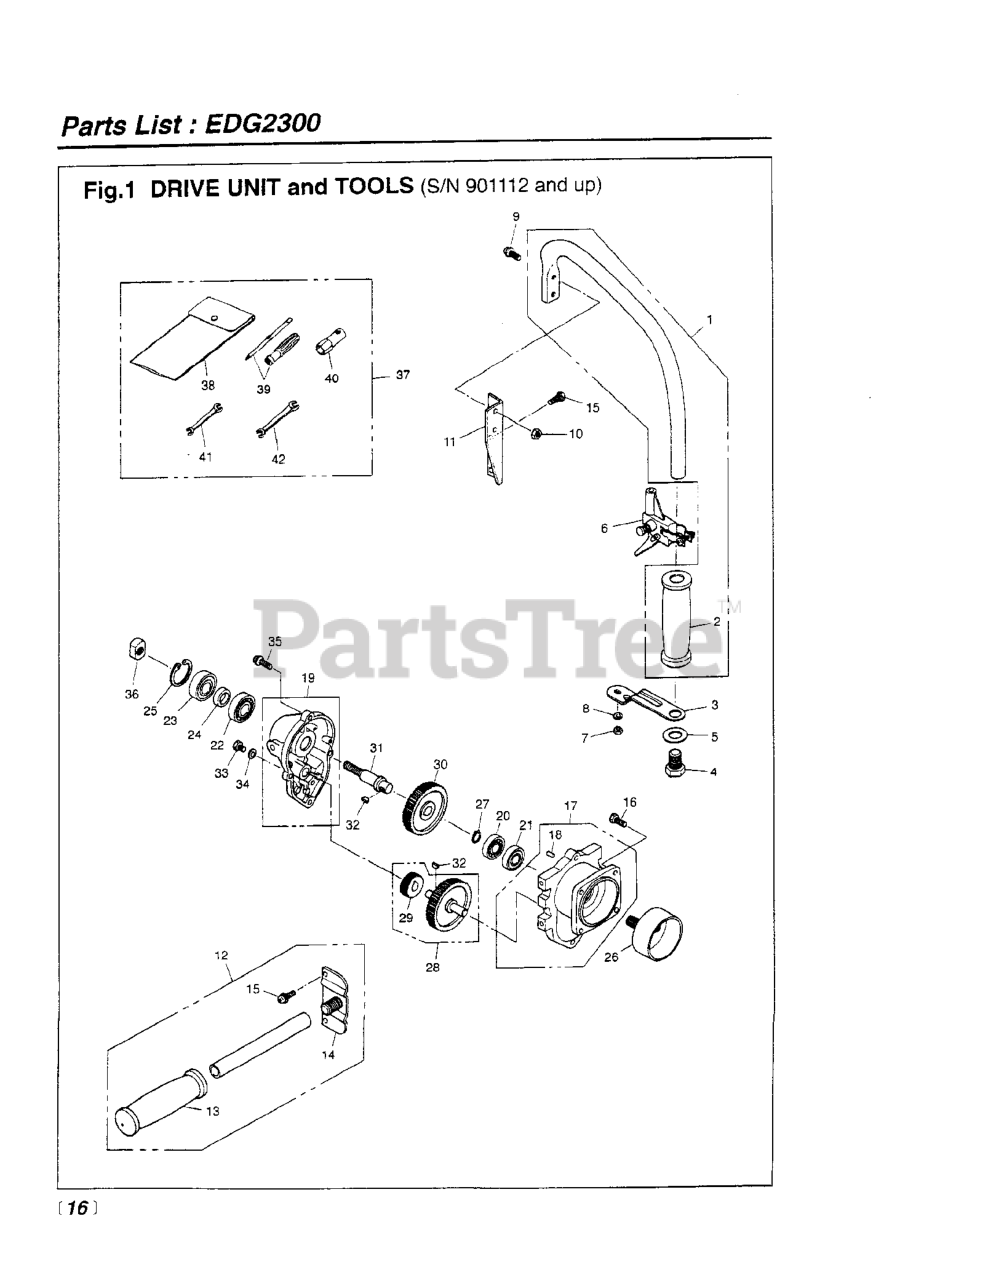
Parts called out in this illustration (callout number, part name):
1	HANDLE(A)
5	WASHER, M14 x 2.3
8	WASHER, SPRING M4 x 1.3
11	BRACKET(A)
12	HANDLE(B)
14	BRACKET(B)
17	CASE A COMP
19	CASE B COMP
25	SNAP RING
31	SHAFT, PTO
37	TOOL SET
